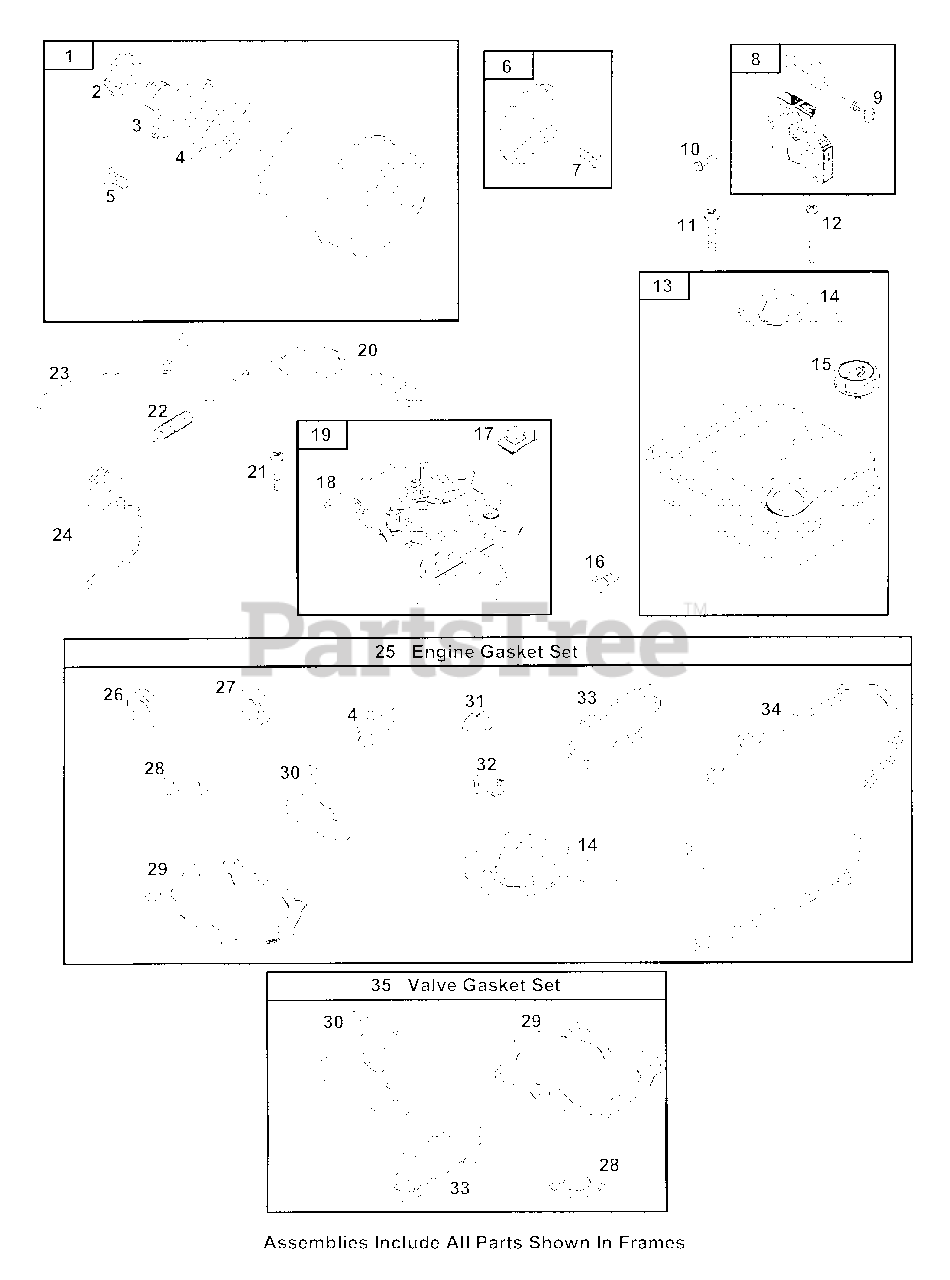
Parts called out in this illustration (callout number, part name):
1	Muffler-Exhaust
2	Muffler/Elbow Locknut
3	Muffler Adapter
4	Exhaust Gasket
5	Screw (Muffler Adapter)
6	Muffler Deflector
7	Screw (Muffler Deflector)
8	Armature-Magneto
9	Sparkplug Terminal
10	Screw (Magneto Armature)
11	Screw, 3/4" Long (Carburetor)
12	Screw, 1 3/4" Long (Carburetor)
14	Fuel Tank Gasket
15	Fuel Tank Cap
16	Screw (Fuel Tank)
17	Switch-Stop
18	Choke Link
19	Speed Control Panel
21	Screw (Speed Control Panel)
22	Governor Spring
23	Link-Air Vane
24	Governor Blade
25	Engine Gasket Set
26	Oil Seal
28	Air Cleaner Gasket
29	Cylinder Head Gasket
30	Intake Gasket
32	Grommet
33	Breather Gasket
